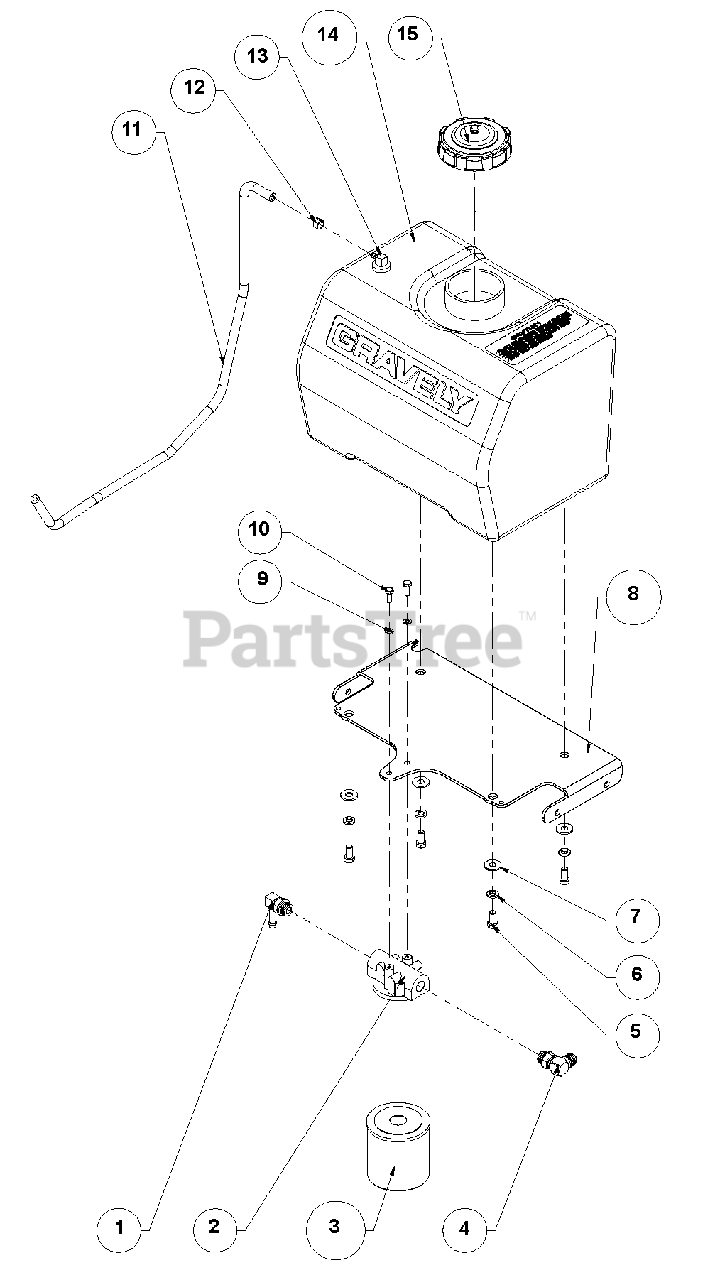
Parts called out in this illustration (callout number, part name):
1	Fitting, 90 BRB-OR
2	Head, Oil Filter
3	Filter, Oil
4	Fitting, 90 .75 MOR x .75 MJIC
5	Bolt, .38-16 x .750 Hex 5
6	Washer, .375 Medium Spring Lock
7	Washer, .375 Regular Flat
8	Bracket, Tank Support
9	Washer, .250 Medium Spring Lock
10	Bolt, 1/4-20 x .750 Hex 5
11	Hose, Fuel .25 x 30.00
12	Clamp, Hose- .50 Spring
13	Fitting, Tank
14	Tank, Fuel
15	Cap, Fuel
